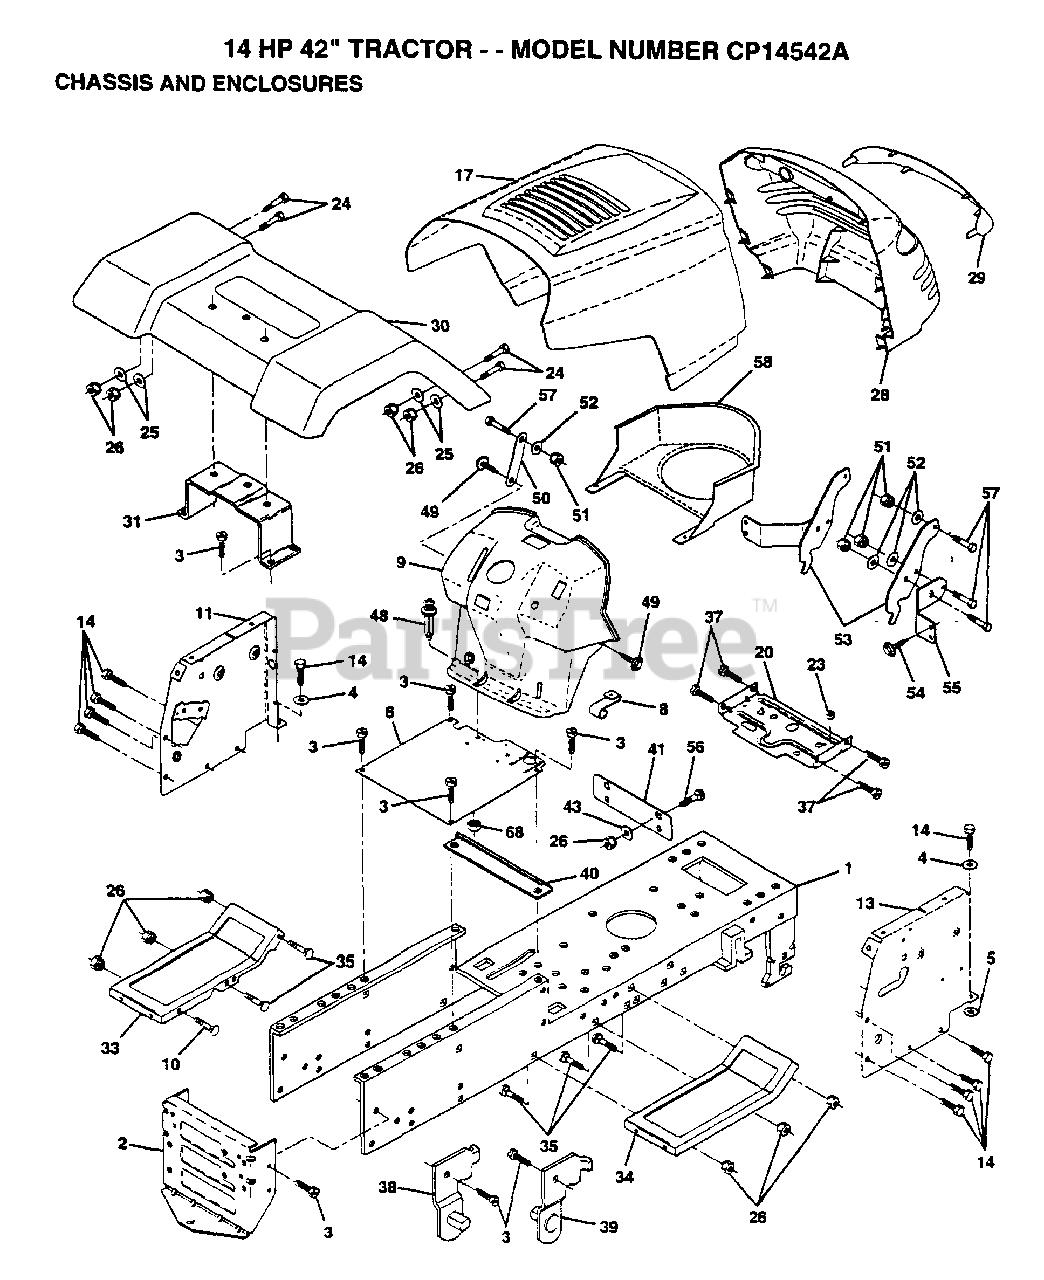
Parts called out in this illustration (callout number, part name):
3	SCREW
4	WASHER
5	LOCKWASHER
8	"CLIP,INSULATOR"
14	SCREW LT
17	HOOD.STL.PRV.LA
24	BOLT
25	WASHER
26	NUT
29	LENS GRILLE
31	BRACKET SUPT FEND
35	BOLT
37	SCREW
38	BRACKET ASM LH
39	BRACKET ASM RH
40	SPACER FENDER LT
41	PLATE EXTEN FEND
43	WASHER
48	RIVET.PUSH.PLATE
49	SCREW HEX CRT
50	BRACE SUPT DASH
51	NUT
52	WASHER
53	HING PICK-OFF HD
55	BRACKET GRILLE
58	DUCT AIR 12-15H
68	NUT
